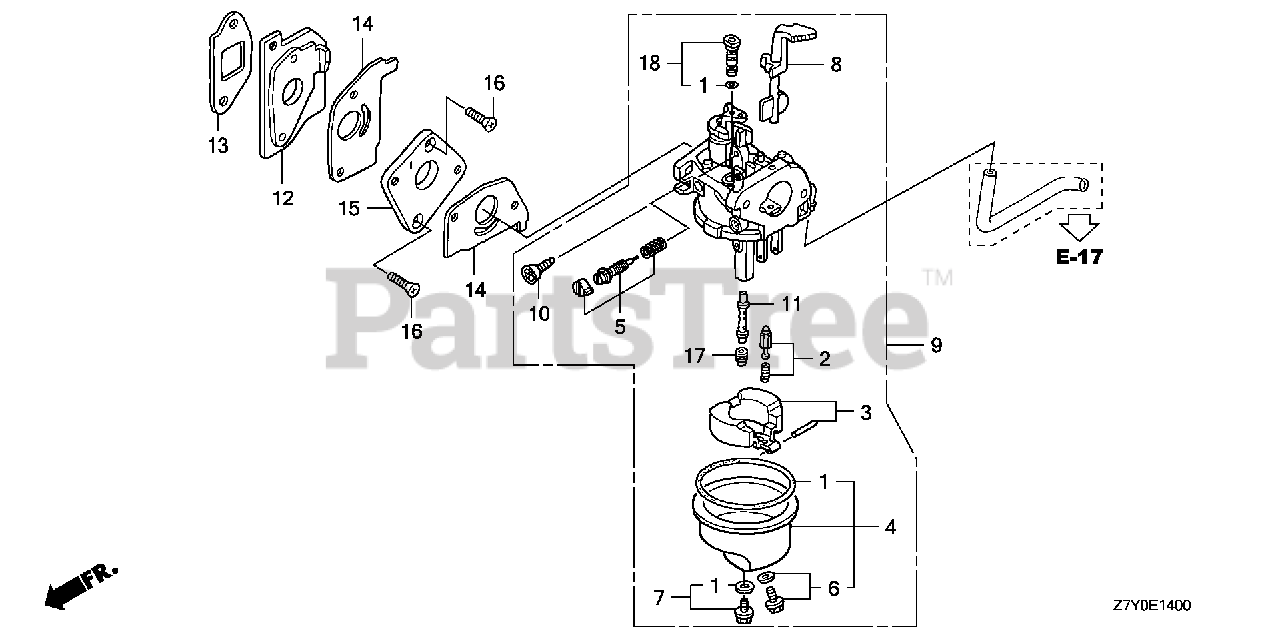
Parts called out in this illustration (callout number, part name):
1	GASKET SET
2	VALVE SET, FLOAT (SEAT NOT INCLUDED)
4	CHAMBER SET, FLOAT
5	SCREW SET, PILOT
6	SCREW SET, DRAIN
7	SCREW SET
9	CARBURETOR ASSY. (BF31K A)
10	SCREW, THROTTLE STOP
11	NOZZLE, MAIN
12	INSULATOR, CARBURETOR
13	GASKET, INSULATOR
14	GASKET, CARBURETOR
15	PLATE, CARBURETOR JOINT
16	SCREW, FLAT (5X20)
17	JET, MAIN (#48)
17	JET, MAIN (#50)
17	JET, MAIN (#52)
18	JET SET, PILOT (#35)
